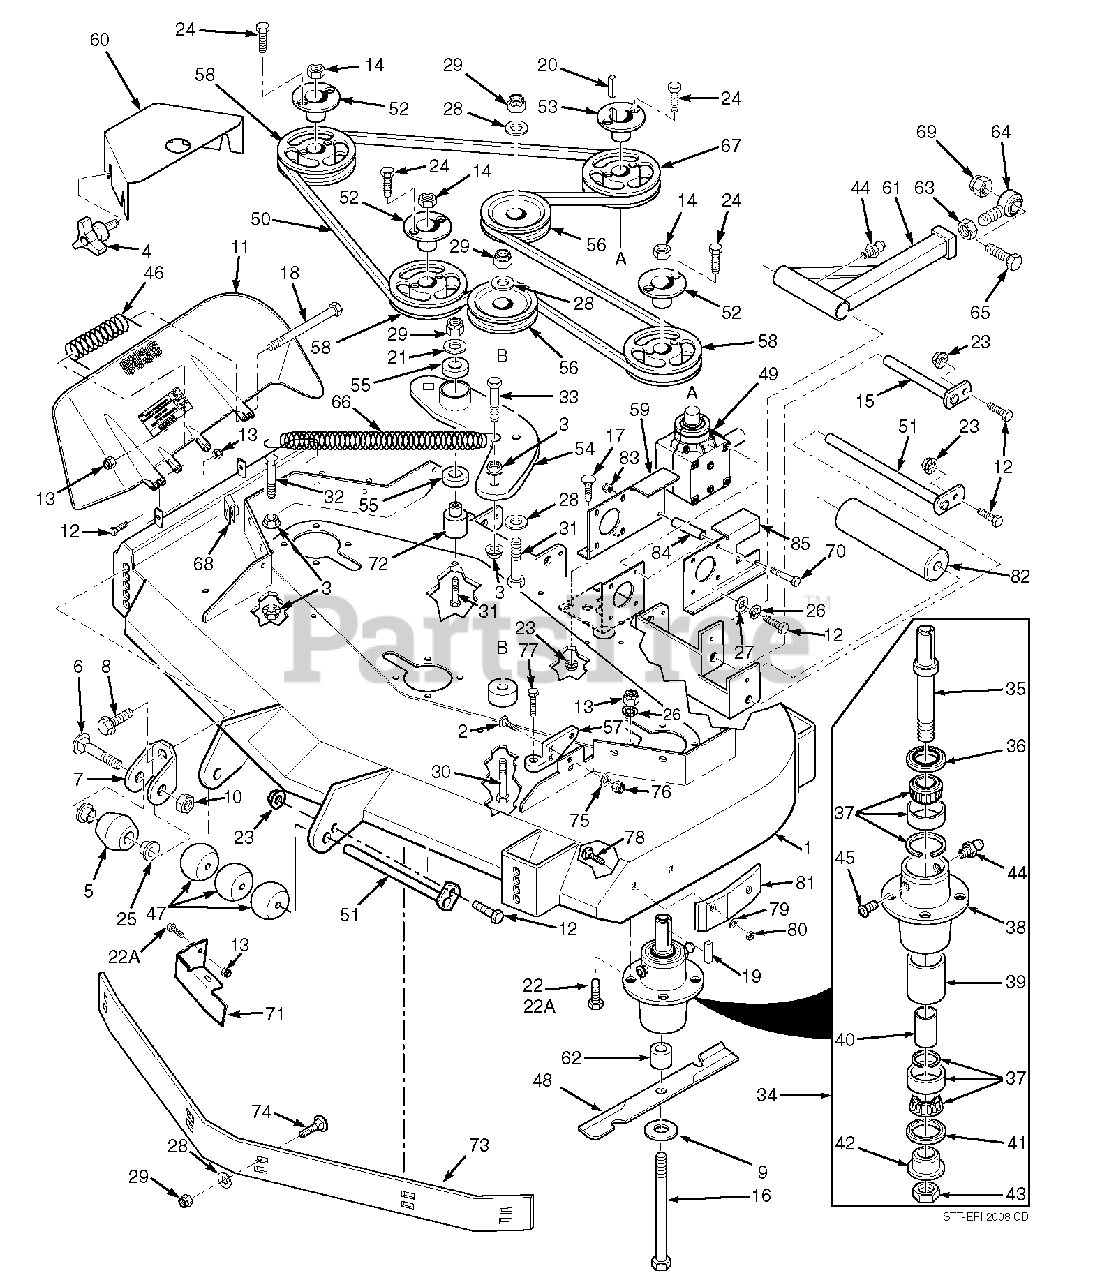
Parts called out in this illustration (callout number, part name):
1	Cutter Deck Velocity Plus
2	Bolt, Carriage 7/16-14 x 1-1/4"
3	Nut, Hex Serr. Flng. 3/8-16
4	Wing Nut, 3/8-16
5	Anti-Scalp Wheel
6	Bolt, Carriage 3/8-16 x 4"
7	Anti-Scalp Wheel Bracket
8	Bolt, Hex Serr. Flng. 3/8-16 x 1"
9	Flatwasher, 5/8" Hardened
10	Locknut, 3/8-16 Center Lock
11	Discharge Chute
12	Bolt, Hex Hd. 5/16-18 x 1-1/2" - Rear
13	Nut, Hex Elastic Stop 5/16-18 Grd. 8
14	Nut, 5/8-11 UNC
15	Pusharm Shaft
16	Bolt, Hex Hd. 5/8-11 x 9-1/2"
17	Bolt, Carriage 5/16-18 x 3/4"
18	Bolt, Hex Hd. 5/16-18 x 4-1/2"
19	Key, 1/4 x 1/4 x 2"
20	Key, 1/4 x 1/4 x 1-1/4"
21	Flatwasher,3/8 (.39 x .938 x .105") HD
22	Bolt, Hex Hd. 5/16-18 x 1-3/4"
23	Nut, Hex Serr. Flng. 5/16-18
24	Bolt, Hex Hd. 1/4-20 x 1" Grd. 8
25	Bushing, .376" I.D. Oilite
26	Lockwasher, 5/16"
27	Flatwasher, 5/16" (.375 x .875 x .083")
28	Flatwasher, 3/8" (.391 x .938 x .105")
29	Nut, Hex Elastic Stop 3/8-16
30	Bolt, Hex Hd. 3/8-16 x 3-1/4"
31	Bolt, Hex Hd. 3/8-16 x 3"
32	Bolt, Hex Hd. 3/8-16 x 1-1/2"
33	Bolt, Hex Hd. 3/8-16 x 1-1/2" Grd. 8
34	Spindle Assembly
35	Spindle Shaft
36	Seal, Top
37	Bearing Assembly
38	Spindle Housing
39	Spacer, Outside
40	Spacer, Inside
41	Seal, Bottom
42	Spindle Bushing, Bottom
43	Nut, Special 1-1/16-18
44	Grease Fitting
45	Relief Fitting, Tapered Spindle
46	Spring, Discharge Chute
47	Wheel, Anti-Scalp
48	Cutter Blade, 21"
49	Gearbox Assembly, Deck Drive
50	Belt, Cutter Deck Drive
51	Roller Shaft
52	Tapered Hub, 1-1/8" Bore
53	Tapered Hub, 1" Bore
54	Idler Arm, Cutter Deck
55	Bearings, Ball
56	Pulley, Idler
57	Lever Assembly, Deck Level
58	Pulley, 6.35" O.D.
59	Mounting Plate, RH Gearbox
60	Belt, Cover
61	Pusharm
62	Spacer, Spindle Bottom
63	Nut, Hex Hd. 5/8-18 UNF
64	Rod End, 5/8" Male RH Thread
65	Bolt, Hex Hd. 5/8-11 x 4-1/2"
66	Spring, Cutter Deck
67	Pulley, 6.75 O.D.
68	U-Nut, 3/8-16
69	Nut, Hex Elastic Stop 5/8-11
70	Bolt, Hex Hd. 5/16-18 x 4-3/4"
71	Discharge Baffl e 61V
72	Pivot, Idler - Short
73	Baffl e, Custom Cut 61V
74	Bolt, Carriage 3/8-16 x 1"
75	Flatwasher, 7/16 (.500 x 1.25 x .083")
76	Nut, Elastic Stop 7/16-14
77	Bolt, Deck Adjust
78	Bolt, Carriage 5/16-18 x 3/4"
79	Flatwasher, 5/16"
80	Nut, Center Lock 5/16-18
81	Wear Pad
82	Wheel, Anti-Scalp
83	Nut, Elastic Stop 5/16-18
84	Spacer, Gearbox Mount
85	Mounting Plate, LH Gearbox
